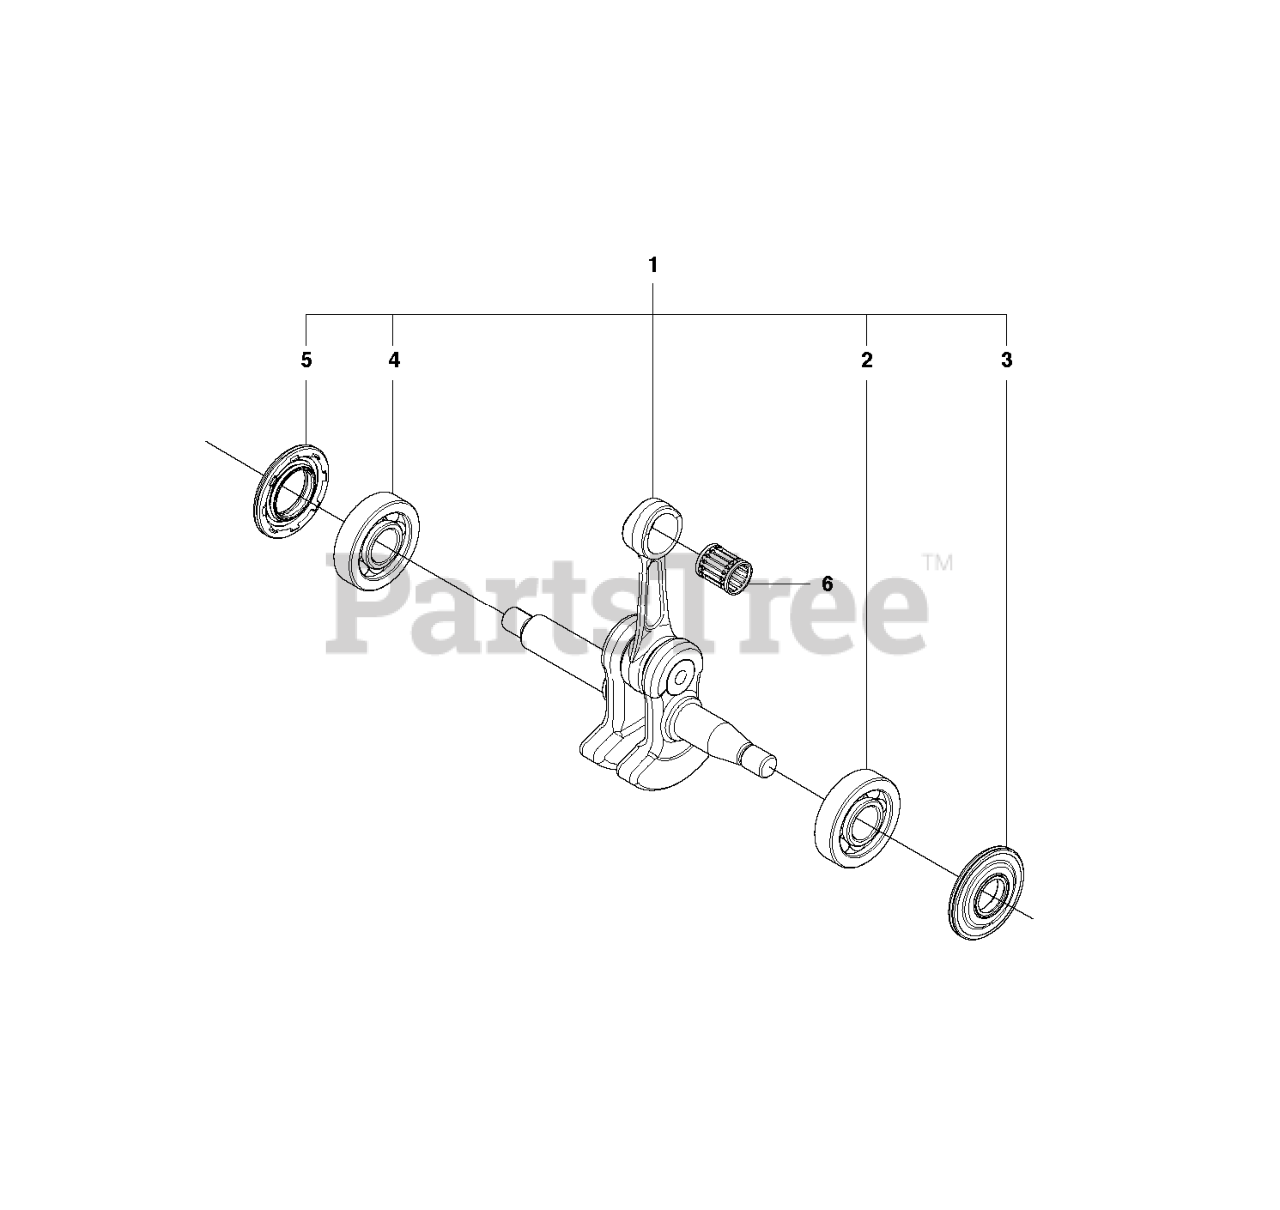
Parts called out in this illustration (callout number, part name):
1	CRANKSHAFT ASSY
2	BALL BEARING
4	BALL BEARING
6	SUPPORT BUSHING
